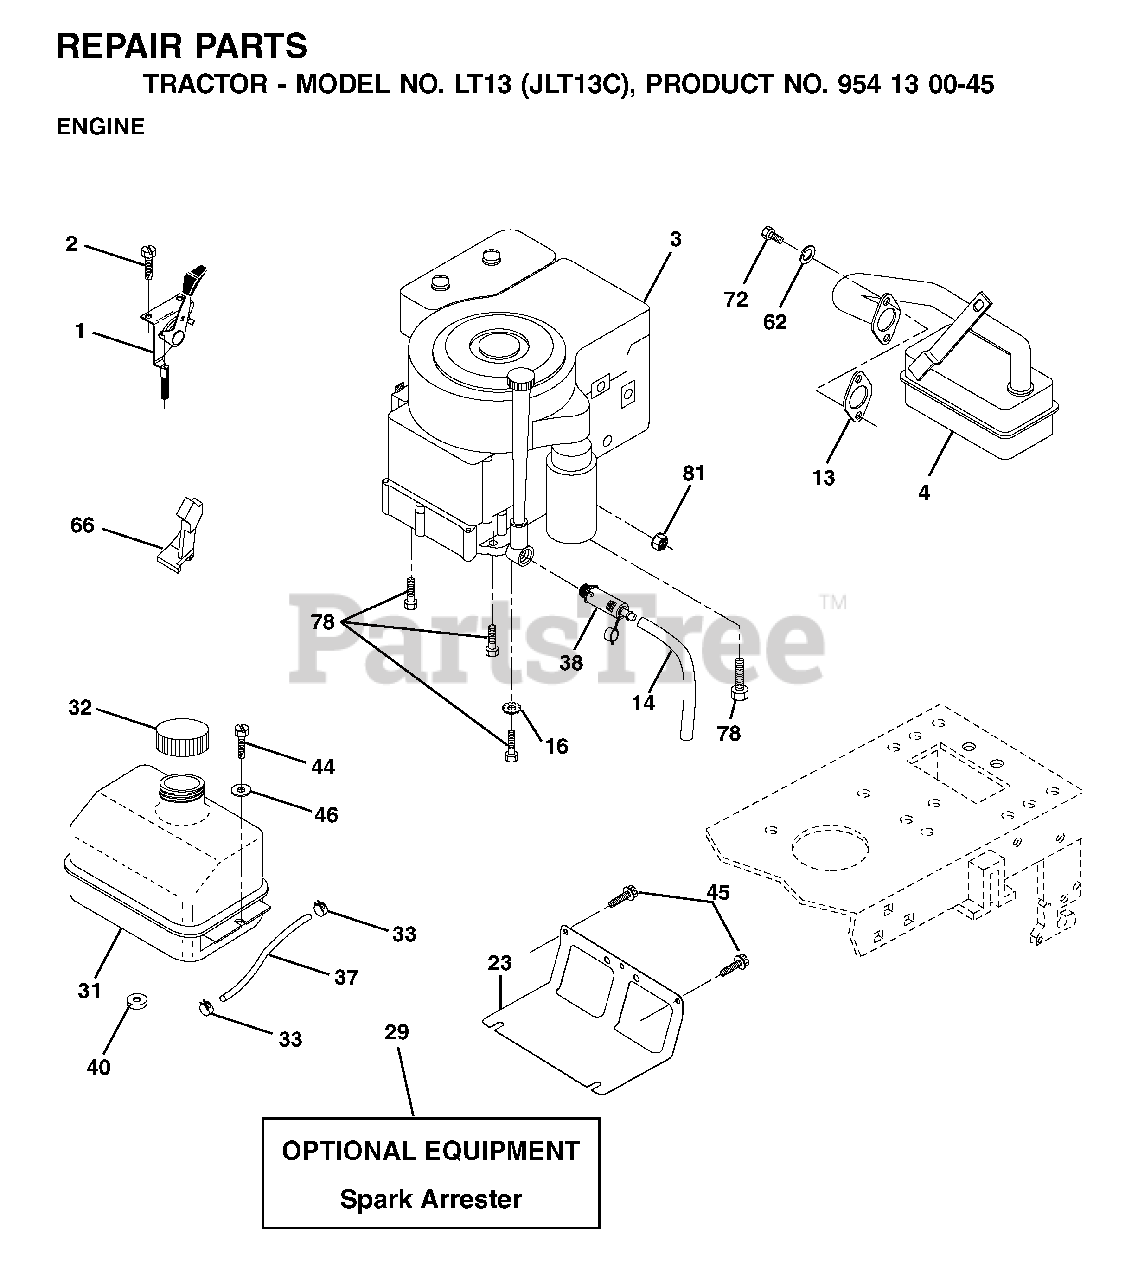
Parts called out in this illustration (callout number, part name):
1	THROTTLE CONTROL CABLE
2	SCREW LT
13	REPL BY 532 27 22-93
14	TUBE, DRAIN OIL ASM.
16	LOCKWASHER
23	SHEILD.BROWNING.DBR.GUARD
29	ARRESTER SPARK (OPTIONAL)
32	FUEL CAP
33	HOSE CLAMP
37	LINE.FUEL.20
38	PLUG, OIL DRAIN EASY
40	GROMMET T
44	SCREW HEXWSHR 1/4-20X3/4
45	SCREW, 3/8-16X3/4
62	LOCKWASHER
66	STOP THROTTLE
72	SCREW
78	SCREW.3/8-16
81	NUT
